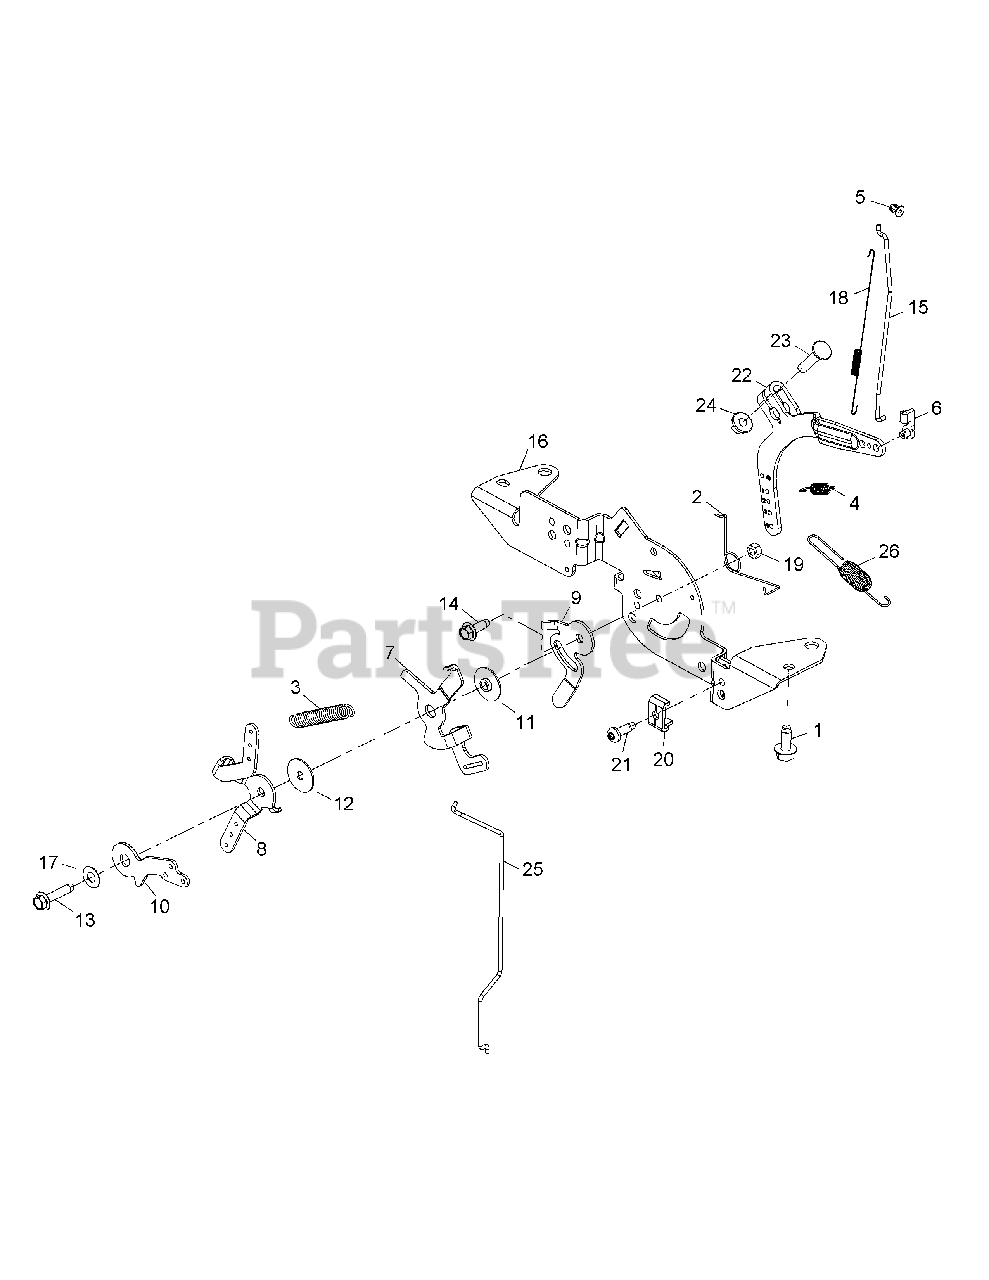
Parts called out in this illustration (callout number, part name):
1	Thread Forming Screw
2	Choke Return Spring
3	Speed Control Spring
4	Governor Spring
5	Linkage Retaining Bushing
6	Throttle Linkage Bushing
7	Governor Spring Lever
8	Speed Control Lever
9	Speed Setting Lever
10	Choke Lever
11	Control Assembly Spacer
12	Flat Washer, 5.5mm
13	Thread Forming Screw
14	Thread Forming Screw
15	Throttle Linkage
16	Control Bracket
17	Spring Washer, 1/4
18	Linkage Spring
19	Lock Nut, M5 x .8
20	Cable Clamp
21	Thread Forming Screw
22	Governor Lever
23	Bolt, M6 x 1.0 x 25
24	Flange Nut, M6 x 1.0
25	Choke Linkage
26	Governor Spring
